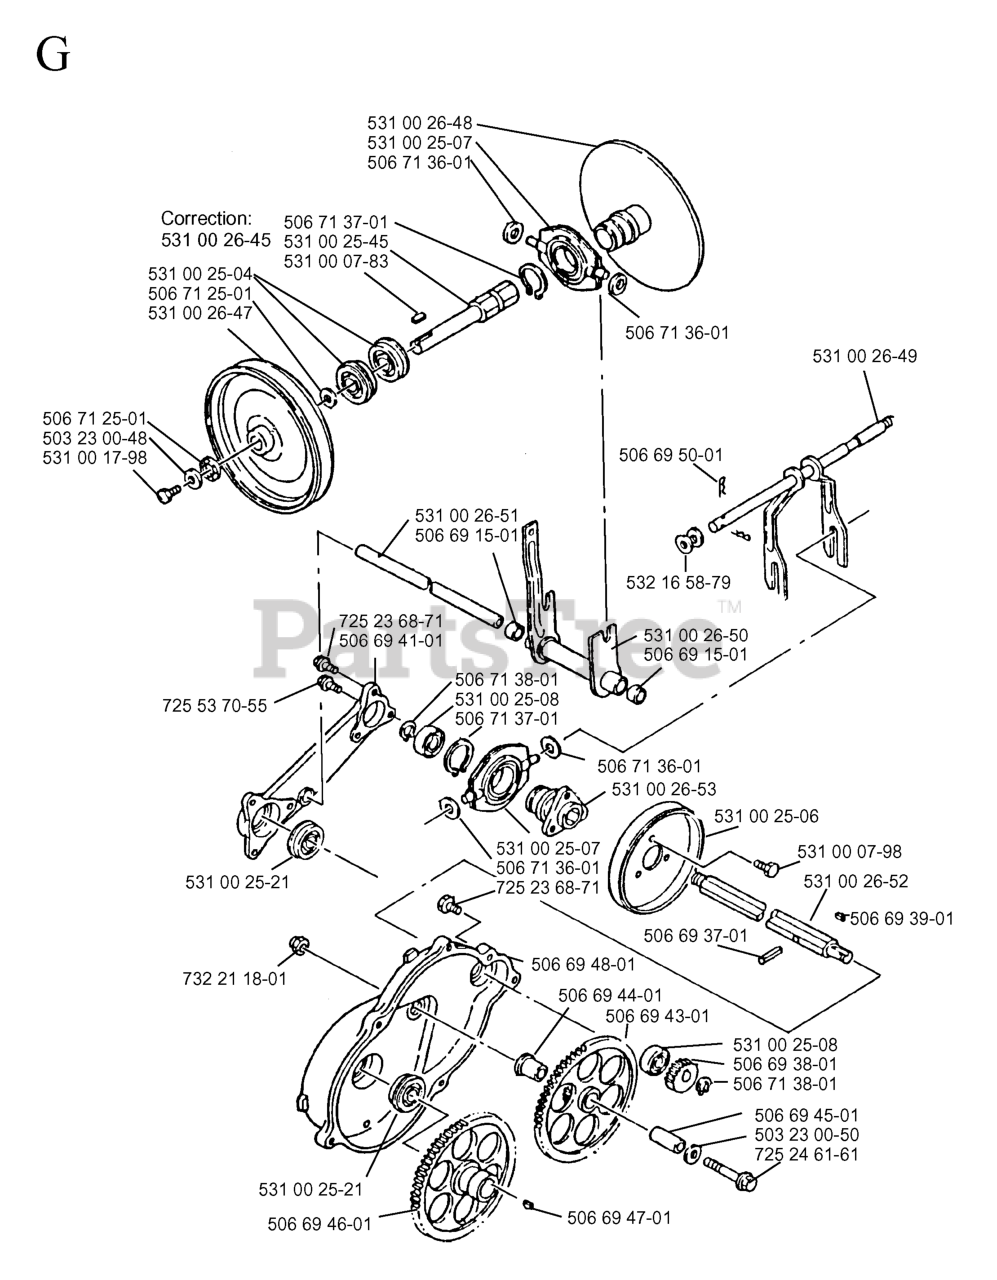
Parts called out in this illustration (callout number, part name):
2	JAM NUT 1/4C (2 2 PW01)
3	BLOWER DECK PLATE
4	42/48 LG DBL HEX STACK PULLEY
6	BELT SHIELD ASSY, 42"
7	DECAL, NO STEP
8	DECAL, BELT DRIVE
9	DRAW LATCH
10	RIVET, BLIND, 5/32 DIA
12	HCS, 7/16-20 X 2 1/2, GR8
13	ZERK
14	RHSNB 1/4C X 3/4
15	WASHER 1/4 FLAT
